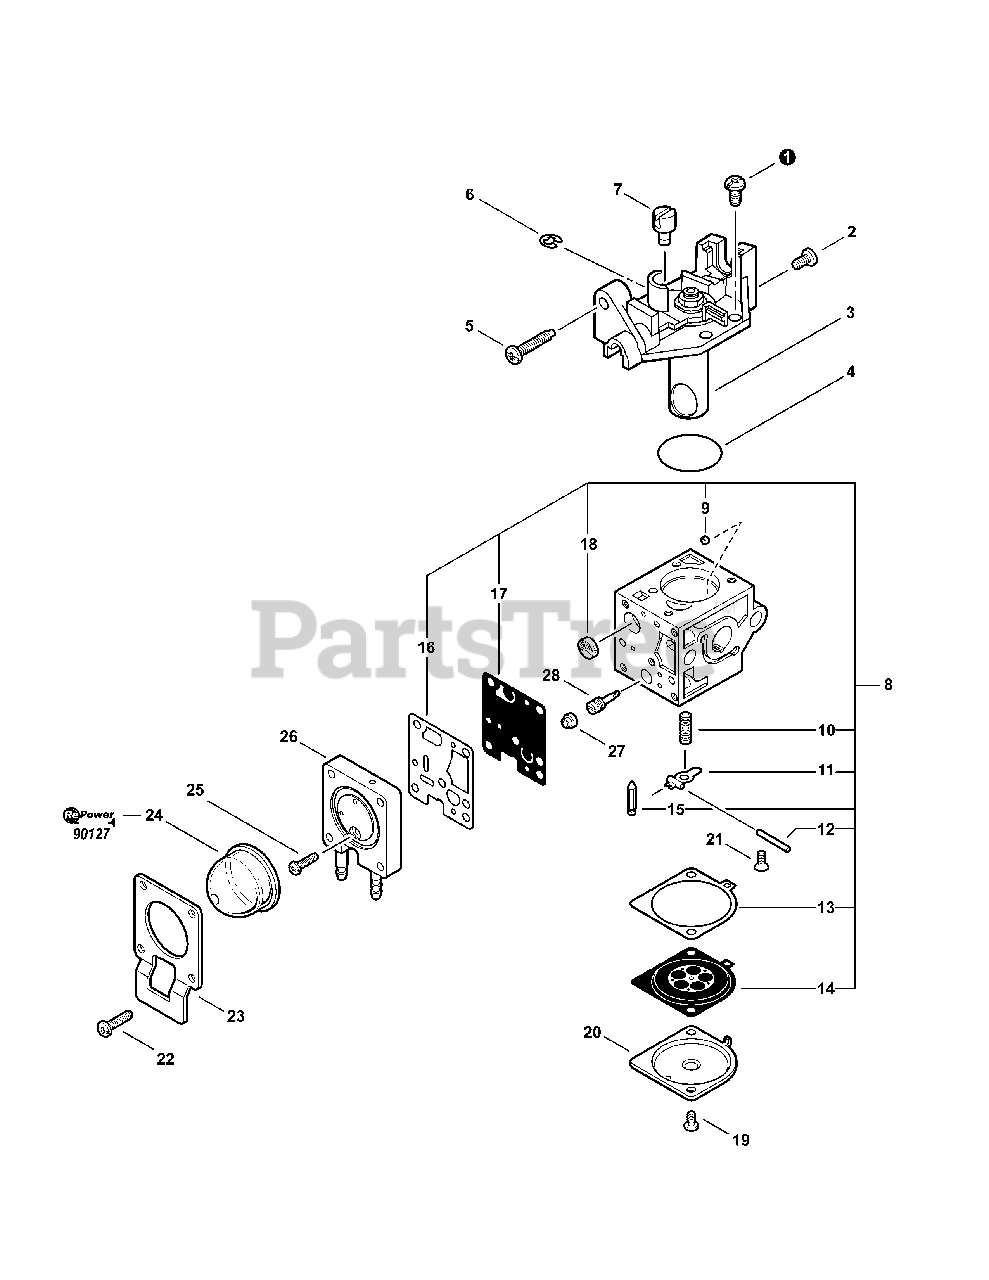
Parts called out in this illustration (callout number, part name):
3	ROTOR COVER ASSY
5	SCREW, IDLE ADJUST
6	RING, RETAINING
8	REPAIR KIT
9	GUIDE, ROLLER
10	SPRING, METERING LEVER
11	LEVER, METERING
12	PIN, METERING LEVER
13	GASKET, DIAPHRAGM
14	DIAPHRAGM, METERING
15	VALVE, INLET NEEDLE
16	GASKET, PUMP
17	DIAPHRAGM, PUMP
18	STRAINER
20	COVER, METERING
21	SCREW, METERING LEVER PIN
22	SCREW, PURGE BULB RETAINER
23	RETAINER, PURGE BULB
24	BULB, PURGE
25	SCREW, PURGE BASE
26	BASE, PURGE
28	NEEDLE - HIGH SPEED
